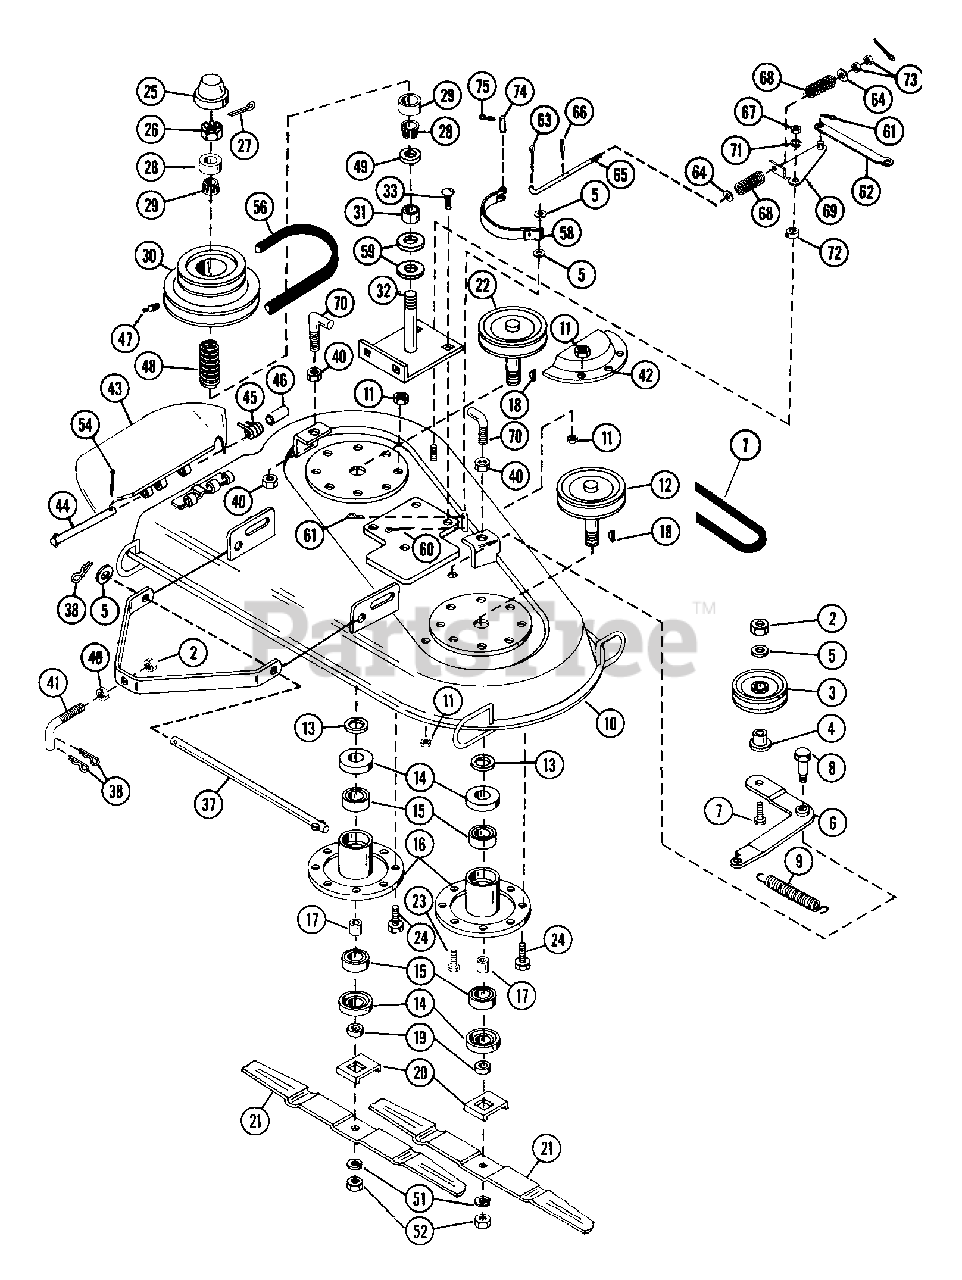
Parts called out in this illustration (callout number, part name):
1	V-BELT, 4L-RAW EDGE
2	NUT-LK-CTR .50-13
3	IDLER-FLAT 2.75X.62
4	BSHG-FLG .500X.625X.500X.750
5	WSHR-FL-STL .505X.880X.072 PL
7	BLT-HEX .50-13X1.25 PL GR2
8	SHOULDER BOLT
9	SG-TENS .091X.73X5.28 WLD 30
10	38 INCH MOWER PAN W/DECALS
11	NUT-LK-CTR .375-16 GR A PL
13	WSHR-FL-STL .755X1.250X.125
14	BEARING SLINGER
15	BRG-BALL .750X1.781X.61
16	SPINDLE HOUSING
17	SPACER .753X1.000X1.140
18	KEY-WDRF .188X.75X.313 SAE 9
19	RETAINER HUB
20	BLADE TRAY
21	MOWER BLADE
22	SHEAVE
23	BLT-HEX .38-16X1.00 PL
24	BLT-HEX .38-16X.75 PL GR2
25	CAP, GREASE
26	NUT-JAM SL .75-20 PL
27	PIN-COTR .12 X 1.25 PL
28	BRG-CONE .750X.61
29	BRG-CUP 1.781X.475
30	SHEAVE 38 IN PAN
31	SPACER .753X1.000X.625
33	BLT-RDHDSQNK .38-16X.75 SHT PL
34	WSHR-FL-STL .382X.812X.062
35	BRACKET
36	BLT-RDHDSQNK .38-16X1.0 PL
37	TOW PIN
38	PIN-HAIR INT .09X.188 PL
39	MOWER STRAP
40	NUT-JAM .50-13 PL
43	CHUTE DEFLECTOR UNIT
44	CLEVIS PIN
45	SG-TORS .090X.37X.63
46	BSHG-SLV .334 X .502 X 1.437
47	SPIN DRIVE ZERK FITTING
48	SG-COMP .091X.950X2.062
49	SEAL .750X1.690X.153
51	WSHR-LK .750X.188 MED PL
52	NUT-JAM .75-10 PL
54	PIN-COTR .09X.75 PL
56	V-BELT, 4L-RAW EDGE
58	BRAKE BAND
59	WSHR-FL-STL .755X1.375X.062 PL
60	PIN-COTR .09X1.0 PL
61	PIN-HAIR INT .08X.38X1.42 YWZC
62	LINK
63	PIN-COTR .06X.50
64	WSHR-FL-STL .323X.625X.062 PL
65	BRAKE ROD
66	PIN-ROLL .125X.75
67	NUT-HEX .312-18
68	SG-COMP .057X.47X1.25
69	BRAKE LEVER
70	HANGER HOOK
71	WSHR-LK .312X.097 PL HVY
73	NUT-JAM .312-18 PL
74	CLEVIS PIN
75	PIN-HAIR INT.06X.25X1.12
